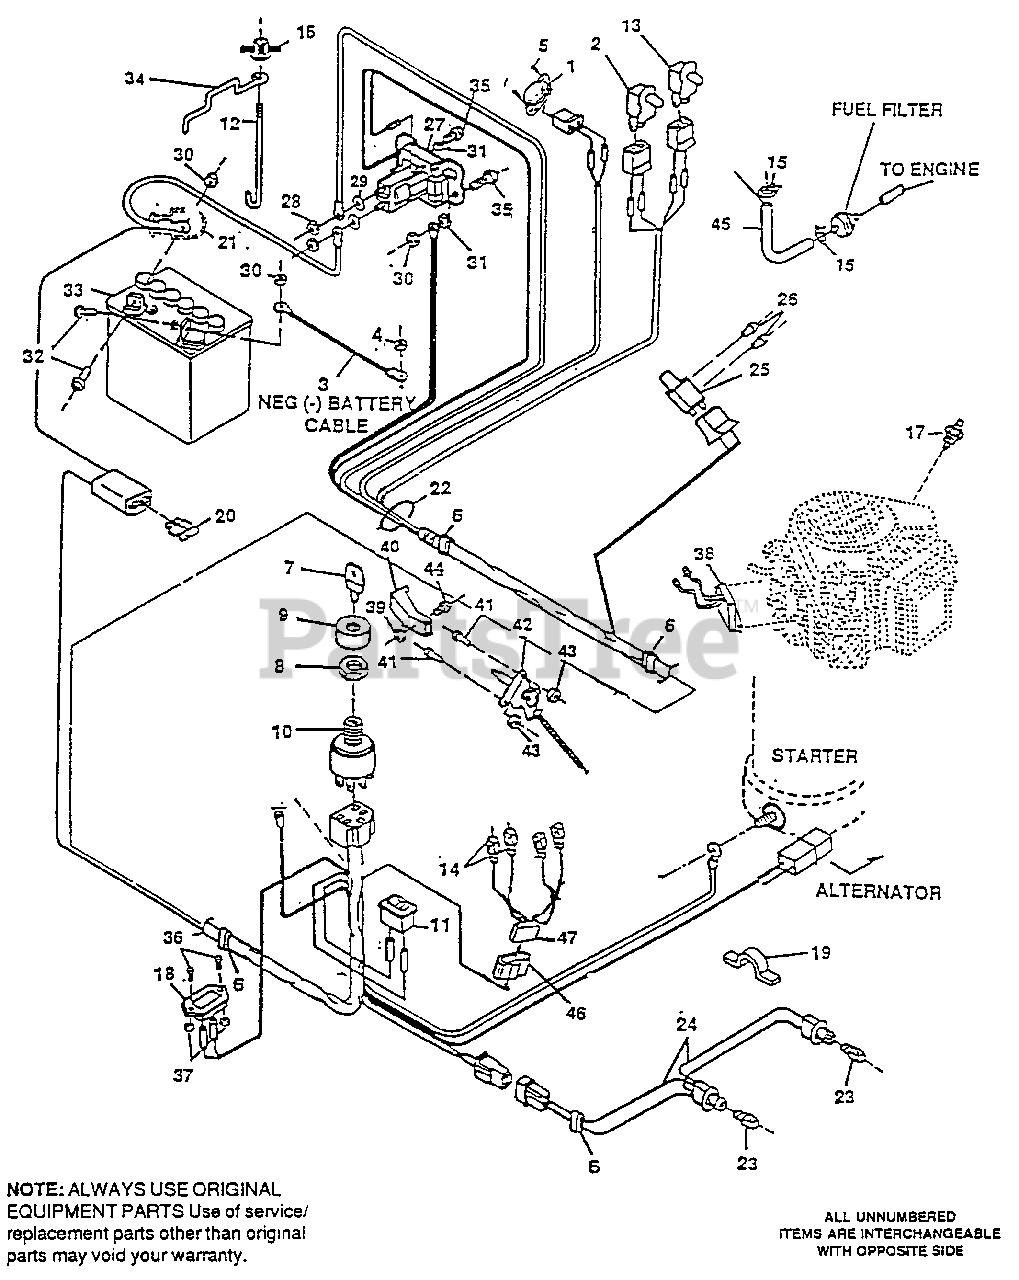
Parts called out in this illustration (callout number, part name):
1	Seat Switch
2	Switch, Snap Mnt No. .140 Blue
3	Cable, Battery, Negative
4	Nut, Hx, Keps, 5/16-18 Thd.
5	Screw, 1/4-20 x .38
7	Key, Ignition Switch
8	Nut, Switch
9	Boot, Switch
10	Switch, Ignition
11	Switch, Light
12	Rod, Battery Hold-Down
13	Switch, Snap Mnt No. .140 Wh.
14	Bulb, Indicator
15	Clamp, Gas Line
17	Oil Sensor
18	Minature Hour Meter
19	Press Clip
20	Fuse, 15A-32V, Spade Type
21	Boot, Rubber (Battery Cable)
22	Wire Harness
23	Bulb Headlamp
24	Assembly, Light Wire
26	Screw, Pn Hd, Tap #12 x 1/2 In.
28	Nut, Hx 5/16-24 Thd.
29	Washer, Lock 5/16 In.
30	Nut, Hx, Keps, 1/4-20 Thd.
31	Nut, Hx, Ctrlk, 1/4-20 Thd.
32	Screw, 1/4-20 x 5/8 In.
34	Bracket, Battery Hold-Down
35	Screw, 1/4-20 x 3/4 In.
36	Screw, #6-32 x .50
37	Nut, Hx Keps 6-32
38	Regulator, Sen. Volt BS with Sensor
39	Nut, Hex. #8-32 Thd.
40	Knob, Throttle Control
41	Screw #10-24 x 5/8
42	Throttle Control
43	Nut, Hex, Nylon Lock #8-32 x 3/8 In.
44	Screw,Ph, Pn, #8-32 x 3/8 In.
46	Low Fuel Wire
47	4-Pin Lamp Holder
